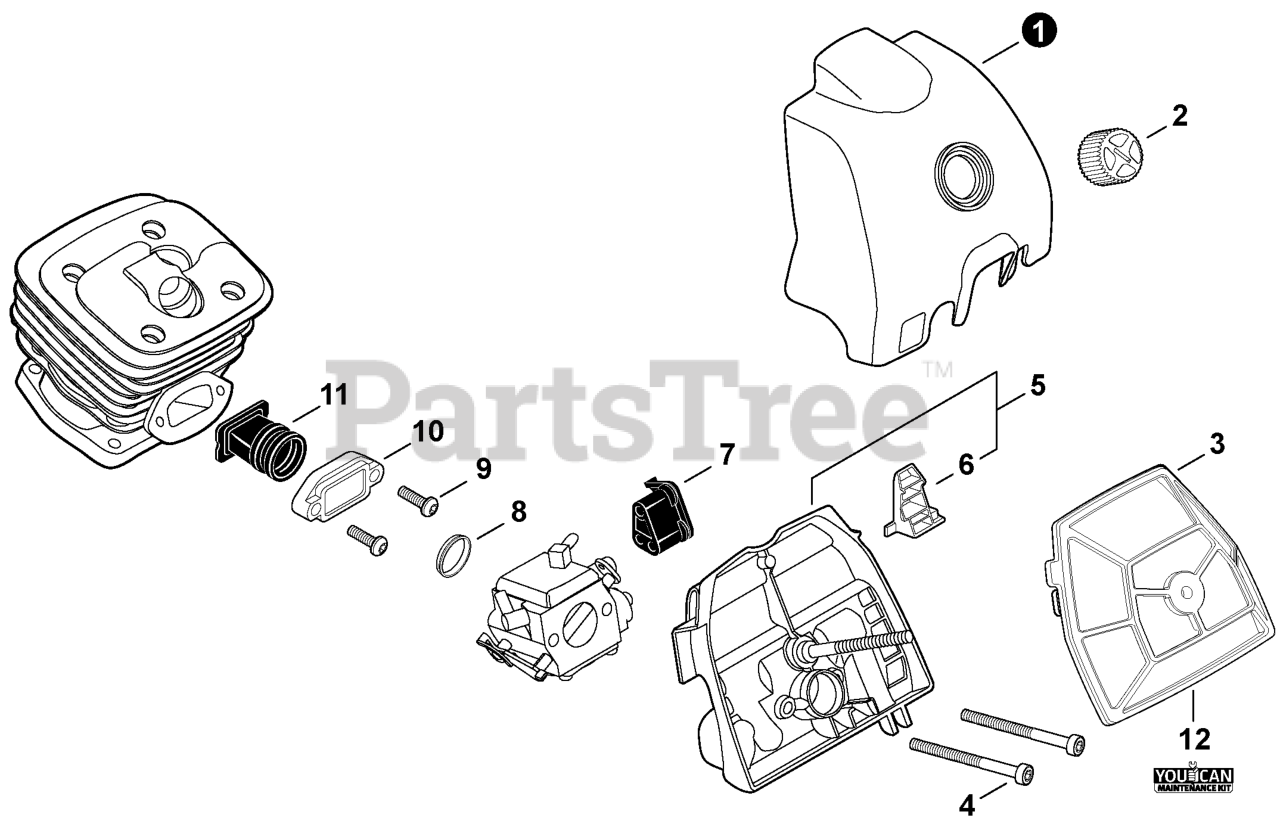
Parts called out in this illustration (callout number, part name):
1	COVER, AIR FILTER
2	KNOB, AIR FILTER COVER
3	FILTER ASSY, AIR
4	BOLT, TORX 5x50
5	CASE, AIR FILTER
6	SHUTTER, AIR
7	GROMMET, NEEDLE
8	COLLAR 18.6x20.4x4
9	BOLT, TORX 5x16
10	HOLDER, BELLOWS
11	BELLOWS, INTAKE
12	TUNE-UP KIT - YOUCAN™
